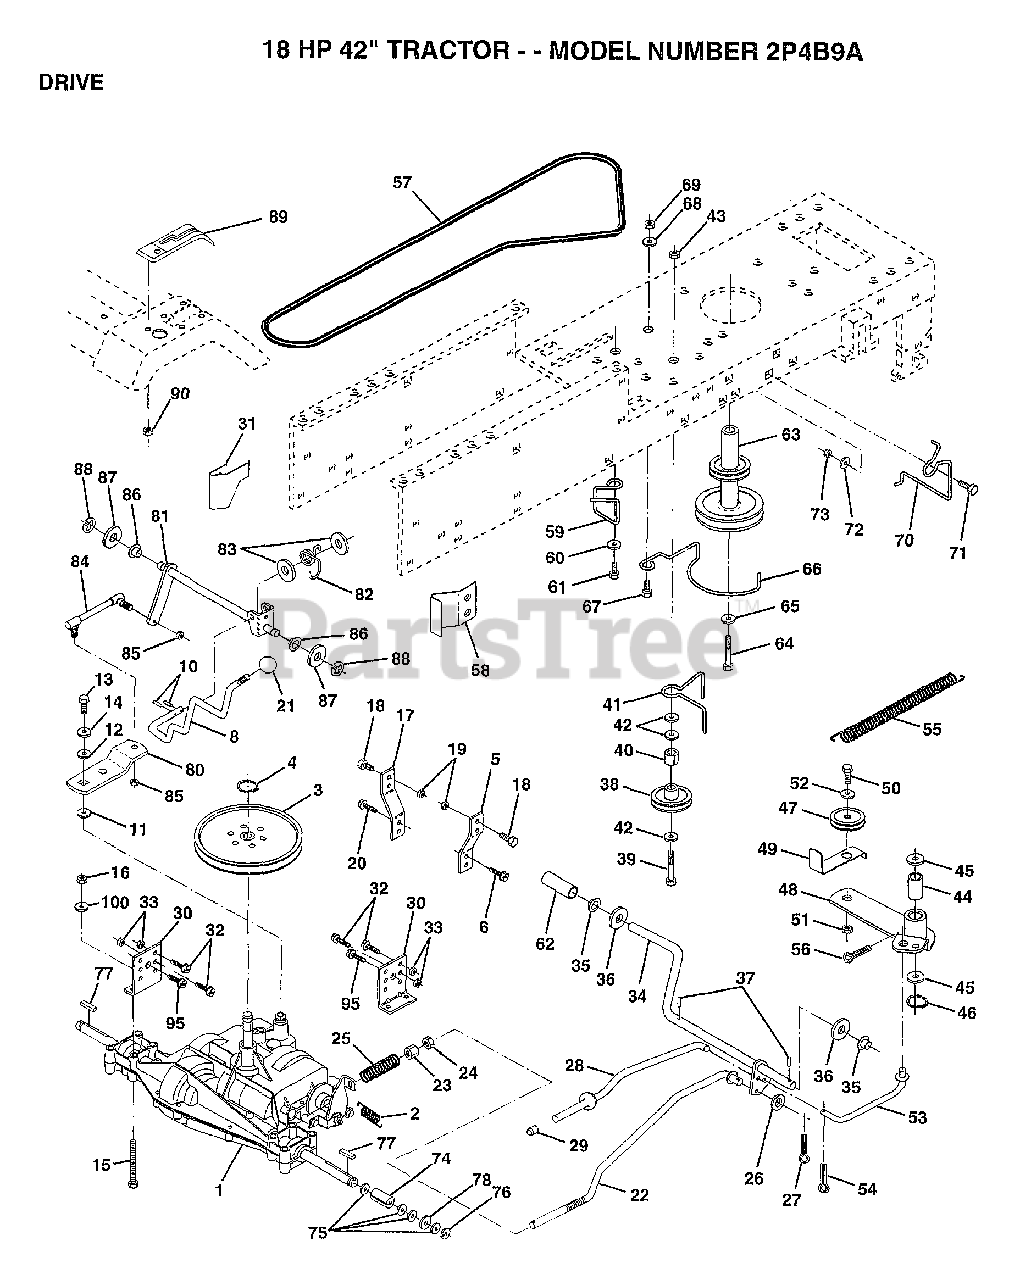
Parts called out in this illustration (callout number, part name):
3	PULLEY TRANS
5	STRAP TORQUE
6	SCREW
8	ROD SHIFT FEND LT
10	PIN COTTER 1/8
11	WASH-SHFT PLT LT
12	WASHER
14	LOCKWASHER
15	BOLT HEX
16	NUT
17	STRAP TORQUE
18	BOLT
19	NUT
20	SCREW
21	KNOB T (1/2-HOLE)
22	BRAKE ROD
23	NUT
24	NUT
25	SPRING ROD LT
26	WASHER
27	COTTER PIN
28	ROD PARK BRAKE
29	PLUNGER CAP T
30	TRANSAXLE MTG BKT
31	"KEEPER,BELT LH T"
32	BOLT
33	NUT
35	NYLON BEARING
36	WASHER LT
38	PULLEY.IDLER.FLAT
39	BOLT
40	SPACER T
41	BELT KEEPER LT
42	WASHER
43	NUT
44	"LY, BEARING"
45	WASHER LT
46	KLIP RING
48	ARM IDLER
49	RETAIN BELT
52	WASHER
53	"LINK, CLUTCH T"
54	COTTER PIN
55	"SPRING, RETURN LT"
56	COTTER PIN
58	"KEEPER,BELT RH T"
59	KEEPER BELT CNTSP
60	WASHER
61	SCREW
62	PEDAL COVER T
63	PULLEY.ENGINE
64	BOLT
65	LOCKWASHER
66	KEEPER.BELT.ENG.L
67	BOLT
68	WASHER
70	KEEPER BELT ENG
71	BOLT
72	WASHER
74	SPACER LT
75	WASHER
76	E-RING LT
77	SQUARE KEY
78	WASHER
80	SHIFT LEVER
81	SHAFT ASM SHIFT
82	"SPRING,TORSION"
83	WASHER
84	TIE ROD
85	NUT 1/4-28
86	BUSHING
87	WASHER D
88	KLIP RING
90	NUT
95	SCREW
100	WASHER M
